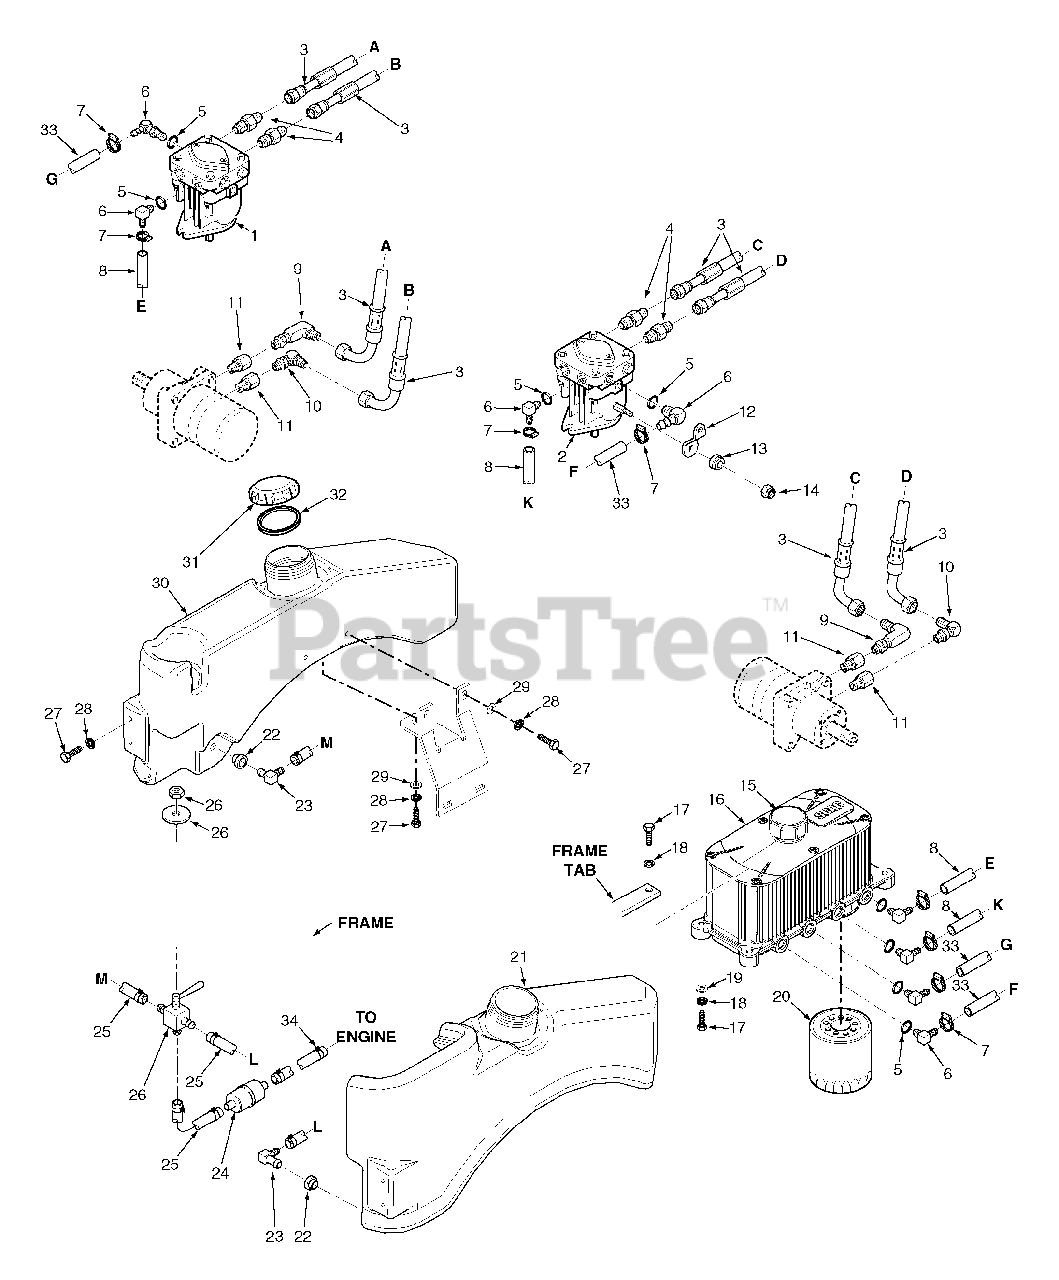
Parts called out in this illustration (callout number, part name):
1	Pump, R.H. BDP-10A (PG-1GCC-D11X-XXXX)
2	Pump, L.H. BDP-10A (PG-1JCC-D11X-XXXX)
3	Hose Assembly, Wheel Motor SZC
4	Fitting, 1/2" JIC x 1/2" O-Ring
5	O-Ring
6	Elbow, 90 Degree O-Ring 9/16-18 x 3/8 Hose
7	Clamp, Hose .69 Max Dia.
8	Hose, 3/8" Pushlock
9	Elbow, 90 Degree JIC to O-Ring
10	Elbow, 90 Degree 1/2 x 1/2" JIC to O-Ring
11	O-Ring Bushing, 5/8"
12	Control Lever, Pump
13	Retainer, Pump Lever
14	Nut, Center Lock 5/16-24
15	Cap, Oil Reservoir
16	Oil Reservoir
17	Bolt, Hex Head 5/16-18 x 1"
18	Lockwasher, 5/16" Spring
19	Flatwasher, 5/16-.375 x .875 x .083
20	Filter, Spin On
21	Fuel Tank, L.H. SZC
22	Tank Bushing
23	Elbow, 90 Degree
24	Fuel Filter
25	Fuel Hose, 1/4 ID
26	Valve, Fuel Shutoff
27	Bolt, Hex Head 5/16-18 x 3/4"
28	Lockwasher, 5/16
29	Flatwasher, 5/16-.375 x .875 x .083
30	Fuel Tank, R.H. SZC
31	Cap, Fuel Tank
32	Gasket, Gas Tank Cap
33	Hose, 3/8" Pushlock Gray
34	Clamp, Fuel Hose 1/4 Hose ID
